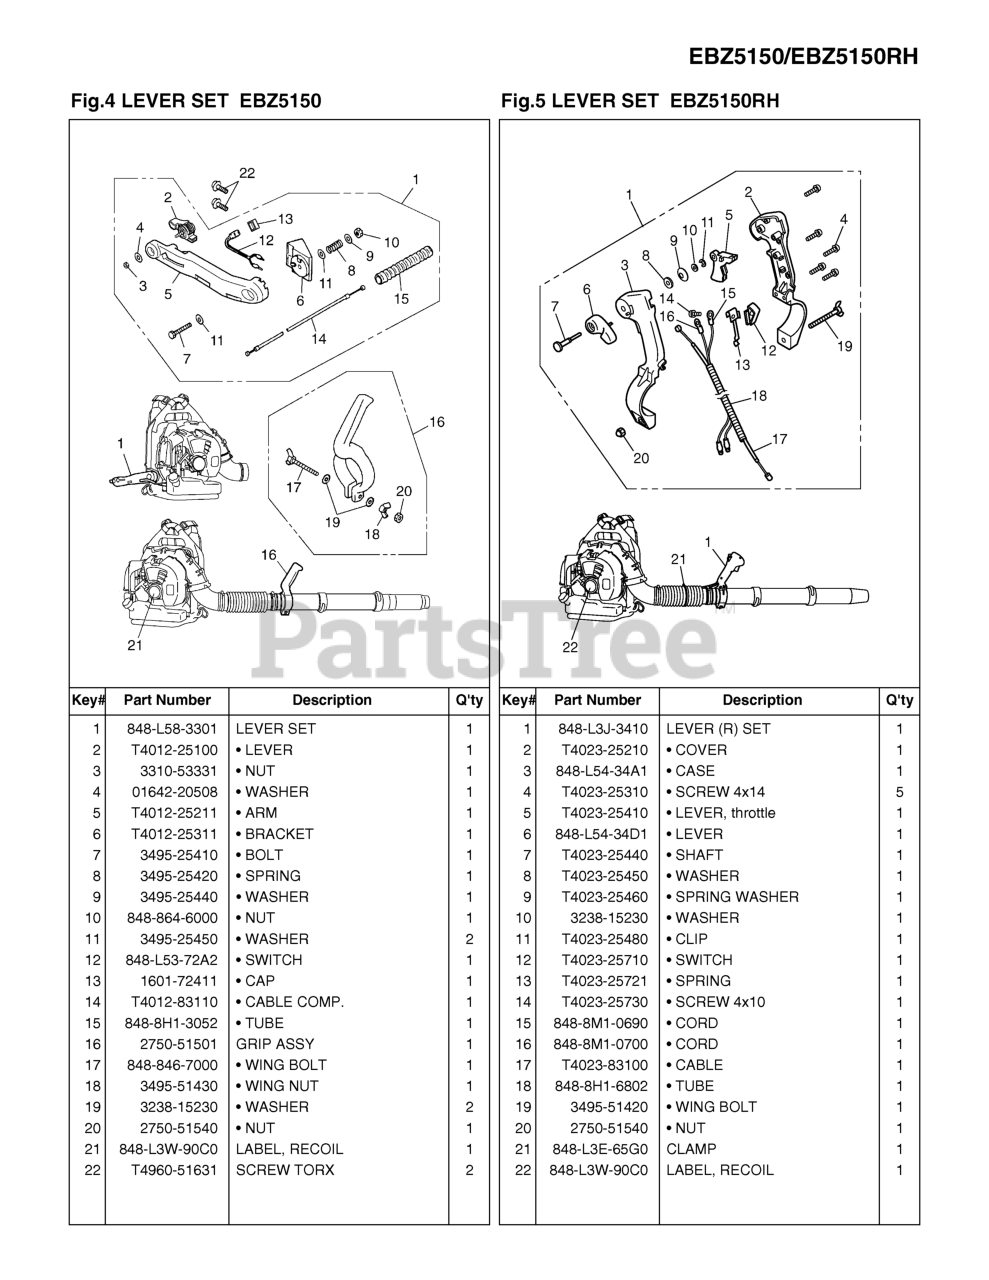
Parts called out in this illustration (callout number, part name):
1	LEVER SET
2	LEVER
3	NUT
4	WASHER
5	ARM
6	BRACKET
7	BOLT
8	SPRING
9	WASHER
10	NUT
11	WASHER
12	SWITCH
13	CAP SWITCH
14	CABLE COMP
15	TUBE (REPLACES T4012-25610)
16	GRIP ASSY
17	WING BOLT
18	WING NUT
19	WASHER
20	NUT
21	LABEL, RECOIL
22	SCREW
